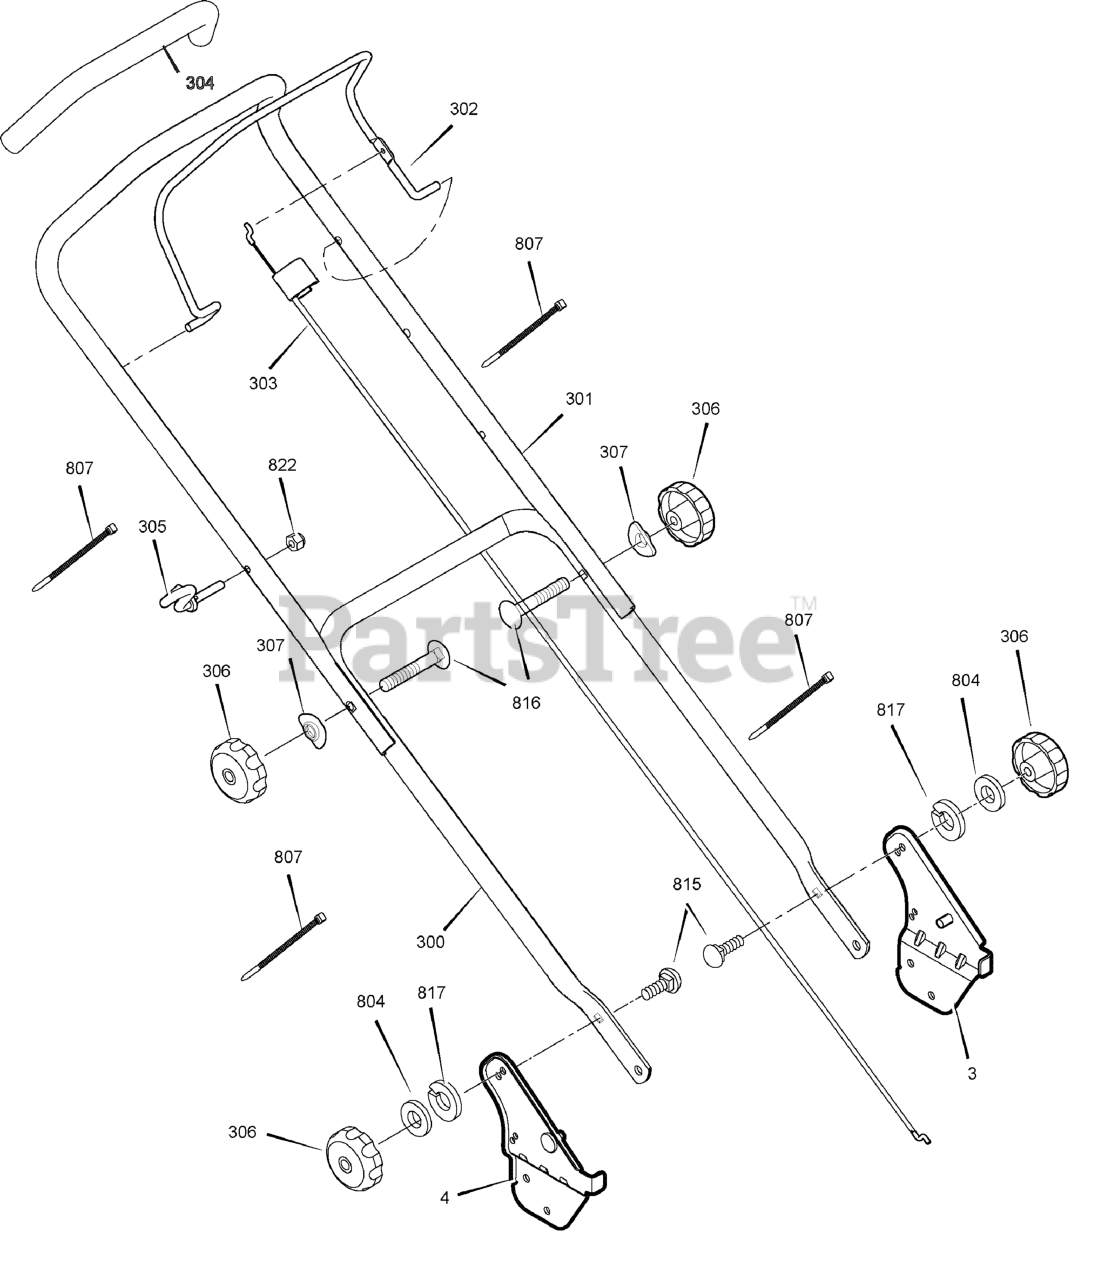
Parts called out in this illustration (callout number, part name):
3	BRACKET ASSEMBLY, Left Handle
4	BRACKET ASSEMBLY, Right Handle
300	HANDLE, Lower
301	HANDLE, Upper
302	LEVER, Engine Stop
303	CABLE, Engine Stop
304	TUBING, Foam
305	GUIDE, Rope
306	KNOB, 5/16-18
307	WASHER, Formed
804	WASHER, 5/8
807	CABLE TIE
815	BOLT, Carriage, 5/16-18 x 1-1/8
816	BOLT, Carriage, 5/16-18 x 2
817	Washer, Lock
822	NUT, Hex, 1/4-20
